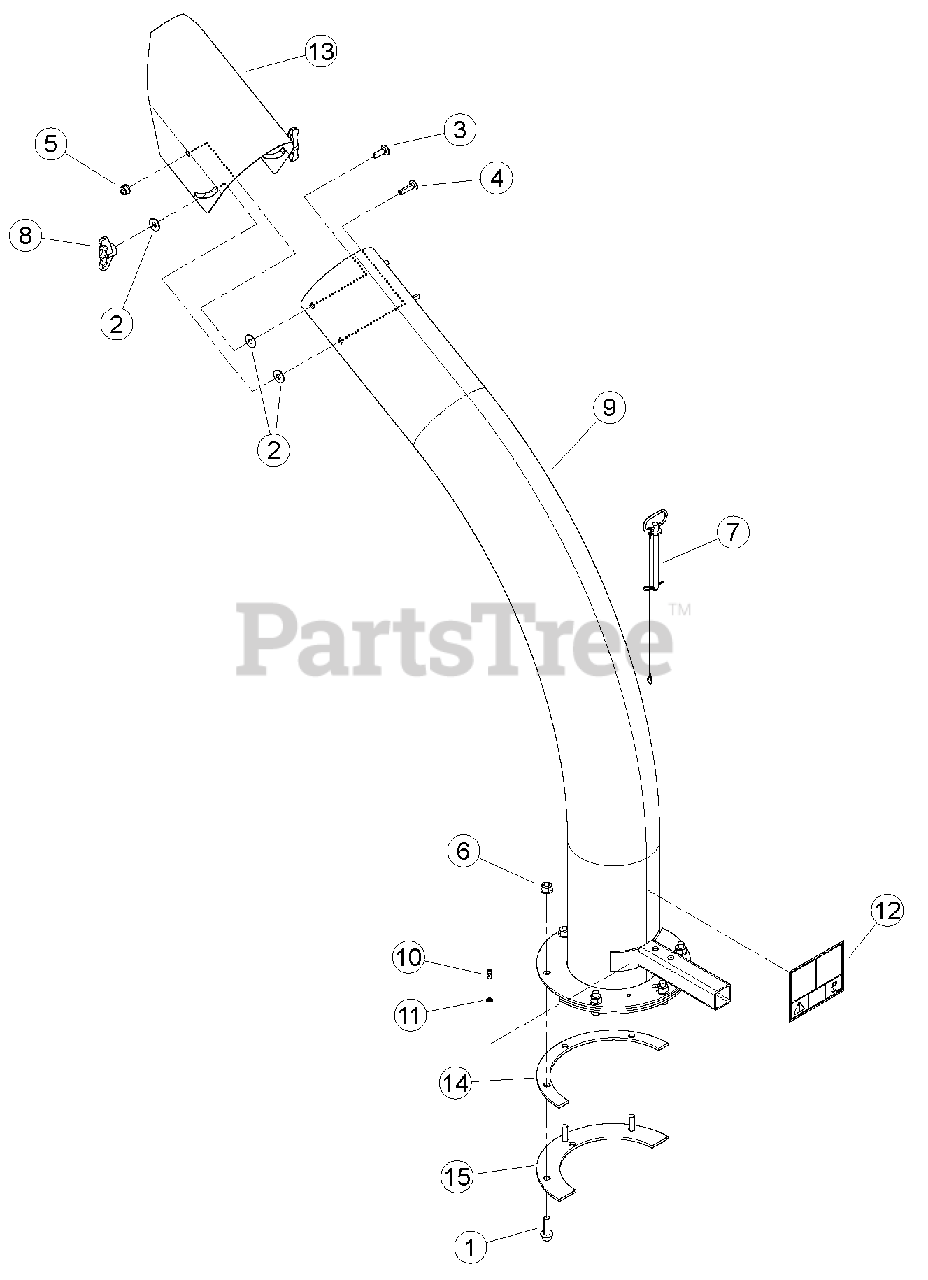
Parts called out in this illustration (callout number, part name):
1	BOLT, 3/8 X 1-1/4 FLANGE NC
2	WASHER, 5/16" FLAT ZP
3	BOLT, 5/16" X 1" GR5 CRG ZP
4	BOLT, 5/16 X 1-1/4" GR5 ZP CRG
5	NUT, 5/16-18 NYLOCK-FLANGE
6	NUT, 3/8-16 NYLOCK FLANGE
7	PIN, 3/8 X 4.25" DISCHARGE
8	KNOB, 5/16-18 UNC TEE W/LOCKING INSERT
9	ASSEMBLY, 6 INCH DISCHARGE CHUTE
10	FITTING, 1/4 SELF-TAP GREASE
11	WASHER, FLAT .254 X .400 X .048
12	DECAL, DISCHARGE DEBRIS & LOCK
13	DEFLECTOR, BLOWER VAC DISCHARGE
14	SPACER, DISCHARGE PIVOT
15	RING, DISCHARGE CLAMP
